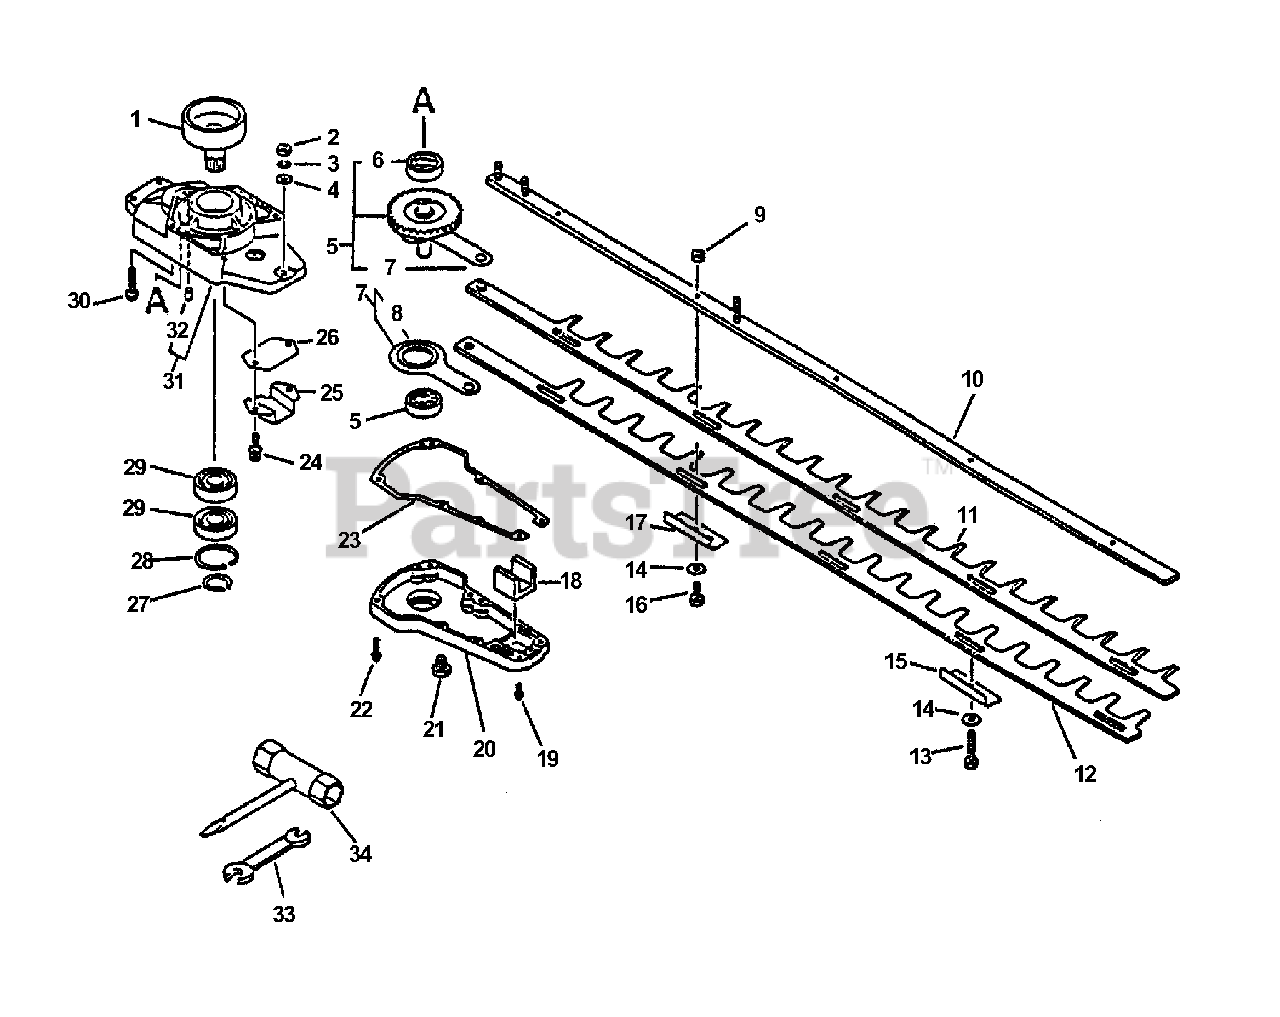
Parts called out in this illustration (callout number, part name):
1	DRUM, CLUTCH
2	NUT, HEX M6
3	WASHER, SPRING 6
4	WASHER 6.5×11.5×0.8
5	GEAR ASSY
6	BEARING, BALL 6200
7	CONNECTING ROD ASSY
8	BEARING, NEEDLE
9	NUT, LOCK 6
10	BAR, FRAME
11	BLADE - UPPER
12	BLADE - LOWER
13	BOLT 6×40
15	INSULATOR
16	BOLT
17	INSULATOR
19	SCREW 4×16
20	LID, GEAR CASE
21	BOLT 8×8 SP
22	SCREW 4×22
23	GASKET, GEAR CASE
24	BOLT 5×14
25	GUIDE
26	GUIDE
27	RING, RETAINING - 16
28	RING, SNAP 35
29	BEARING, BALL 6003
30	SCREW 5×30
31	CASE, GEAR
32	PIN, LOCATING 4
33	SPANNER 8×10
34	WRENCH 14×19 W/S.DRIVER
